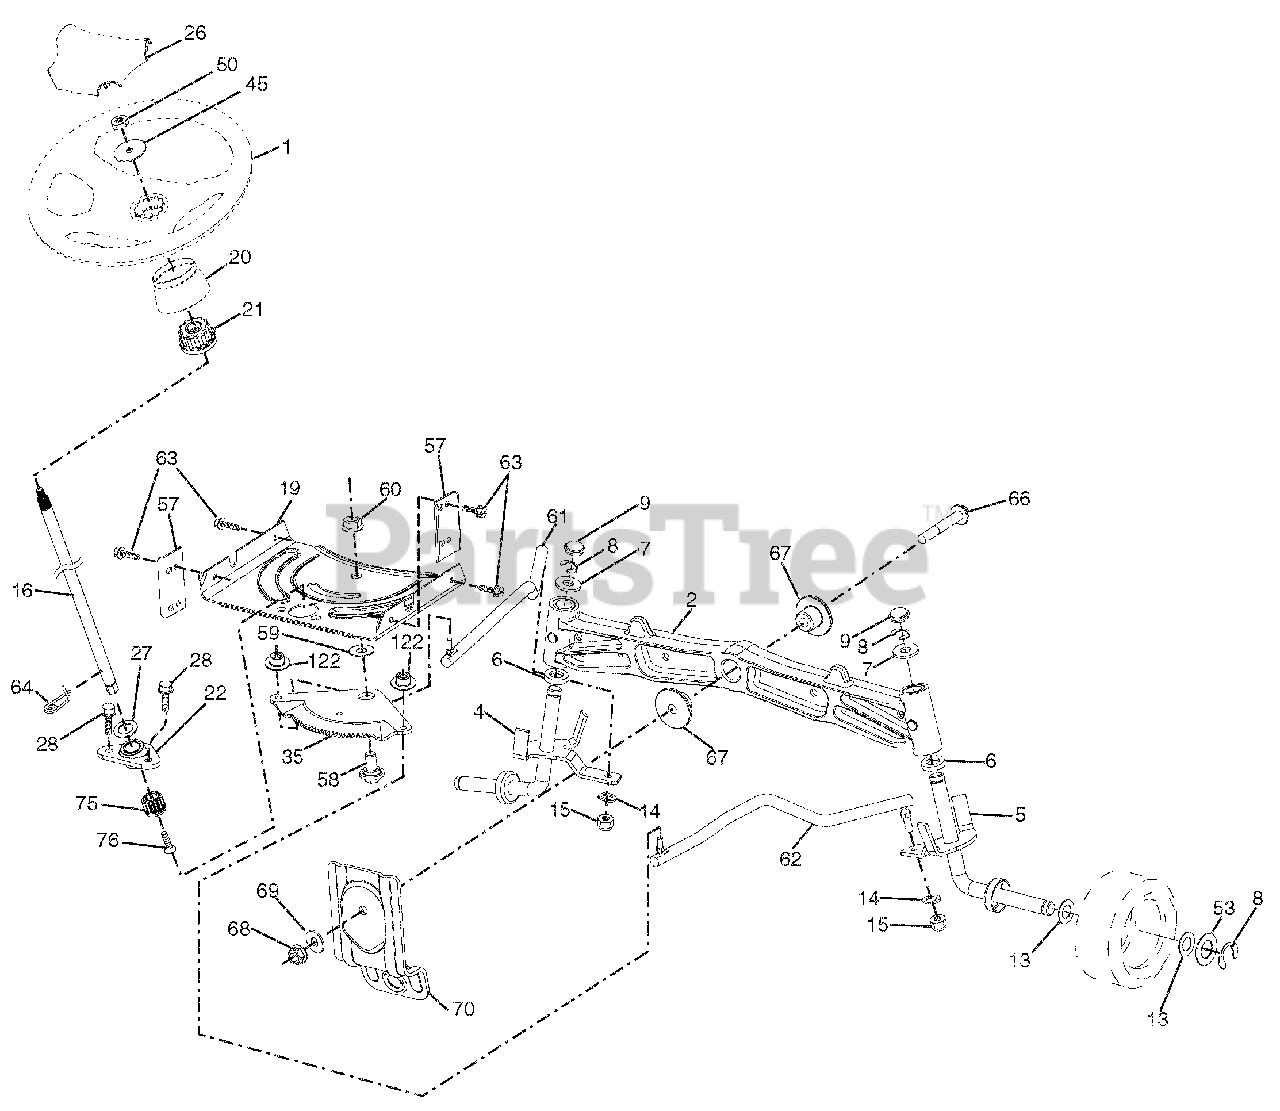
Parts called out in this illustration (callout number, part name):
1	WHEEL STEERING
2	AXLE.CAST IRON
4	SPINDLE.WELDED.LH.15"TEX
5	SPINDLE.WELDED.RH.15"TEX
6	WAHSER THRUST .75 X 1.230
7	WASHER.25/32 X 1-5/8 X 16GA.
8	RING.KLIP.#T5304-75
9	CAP.SPINDLE.FR.TOP.BLK.
13	WASHER.25/32 X 1 1/4 X 16 GA.
14	Washer, Lock 3/8
15	NUT.CROWNLOCK.3/8-24
16	SHAFT STEER
19	PLATE.STEER.DDL.NLT/NGT
20	BOOT.STEERING
21	ADAPTER.STEER
22	STEER.SUPT. LOWER
26	CAP WHEEL STEERING HRS/SRS BLK
27	WASHER 21/32 X 1 X 1 GA.
28	SCREW.HEXWSH THDR3/8-16X3/4.BL
35	GEAR SECTOR.PLATE.DDL.NLT/NGT
50	Nut, Hex, Flangelock 3/8-16
53	WASHER.HARDEN..793 X 1.637X060
57	BRACKET.UPSTOP.TEX
58	BOLT.SHOULDER.SECTOR.PIVOT.CFM
59	WASHER.THRUST.SECTOR.STEER.NLT
60	NUT.FLANGE LOCK.5/8-11
61	DRAGLINK.LH.BALLSTUD.DDL.
62	DRAGLINK.RH.BALLSTUD.DDL
63	SCREW.5/16-18X3/4.SMGML.TAP/BL
64	RETAINER.CLIP.SPRING.STEERING
66	BOLT.HEX.FGHD.7/16-14 X 3.SERR
67	BUSHING.PM.FRONT AXLE
68	NUT.LOCK.FLANGE.7/16-14.GR5
69	WASHER.1.5 X .505 X .118
70	BRACKET.DECK.SUSPENSION.FRONT
122	CAP GEAR SECTOR
